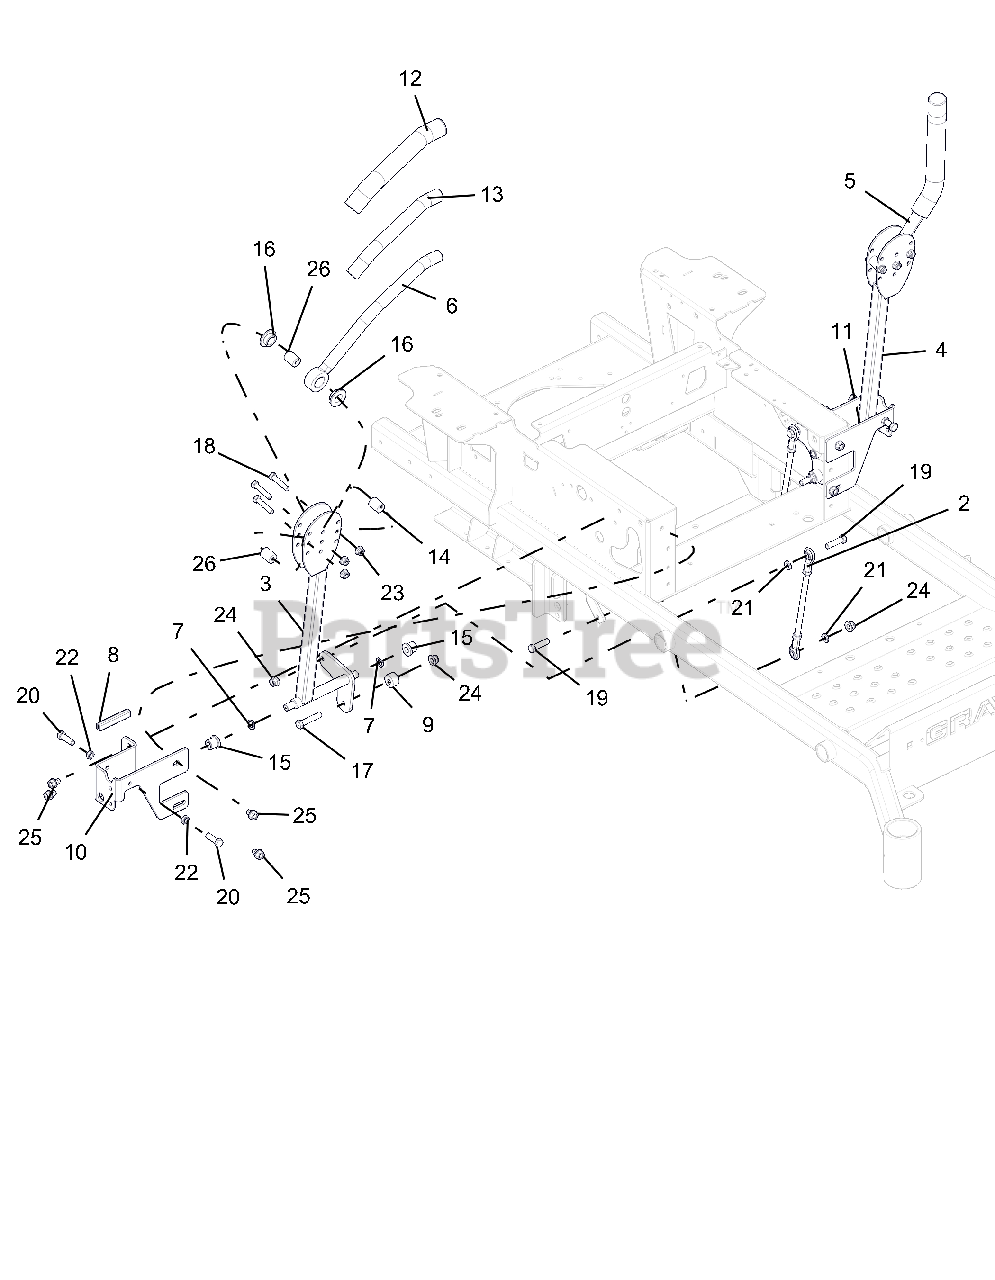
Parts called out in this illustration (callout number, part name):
2	ASM, STEERING LINKAGE
3	WLDMT, PT/PT100 CONTROL ARM-BLACK
4	WLDMT, LH PT/PT100 CONTROL ARM
5	WLDMT, LH HANDLE
6	WLDMT, RH HANDLE
7	WAVE WASHER .531X.781X.125 FH
8	STRIP, COWL - 1.50 LG
9	SPACER .390X1.000X.562
10	BRKT, RH STEERING STOP-RED
11	BRKT, LH STEERING STOP-RED
12	GRIP, HANDLEBAR
13	TUBE, .88ID X 1.00OD X 10.25
14	BSHG, ECCENTRIC .328 X .750 X .970
15	BHSG-FLG .500X.750X.750X.125
16	BSHG, FLANGE .762 X 1.48 X .44 NYLON
17	BLT-HEX .38-16X2.00 FTH GR5 YWZC
18	BLT-HEX .31-18X1.75 GR5 YWZC
19	BLT-HEX .38-16X1.50 GR5 YWZC
20	BLT-HEX .38-16X1.25 GR5 YWZC
21	WSHR-LK .38X.094 REG YWZC
22	NUT, JAM .375-16 YWZC
23	NUT-LK-NYL-FLG .31-18 YWZC
24	NUT-LK-NYL-FLG .38-16 YWZC
25	SCR-TAP .38-16X.50 HWH TR YWZ
26	SPACER, .328 X .76 X 1.01
